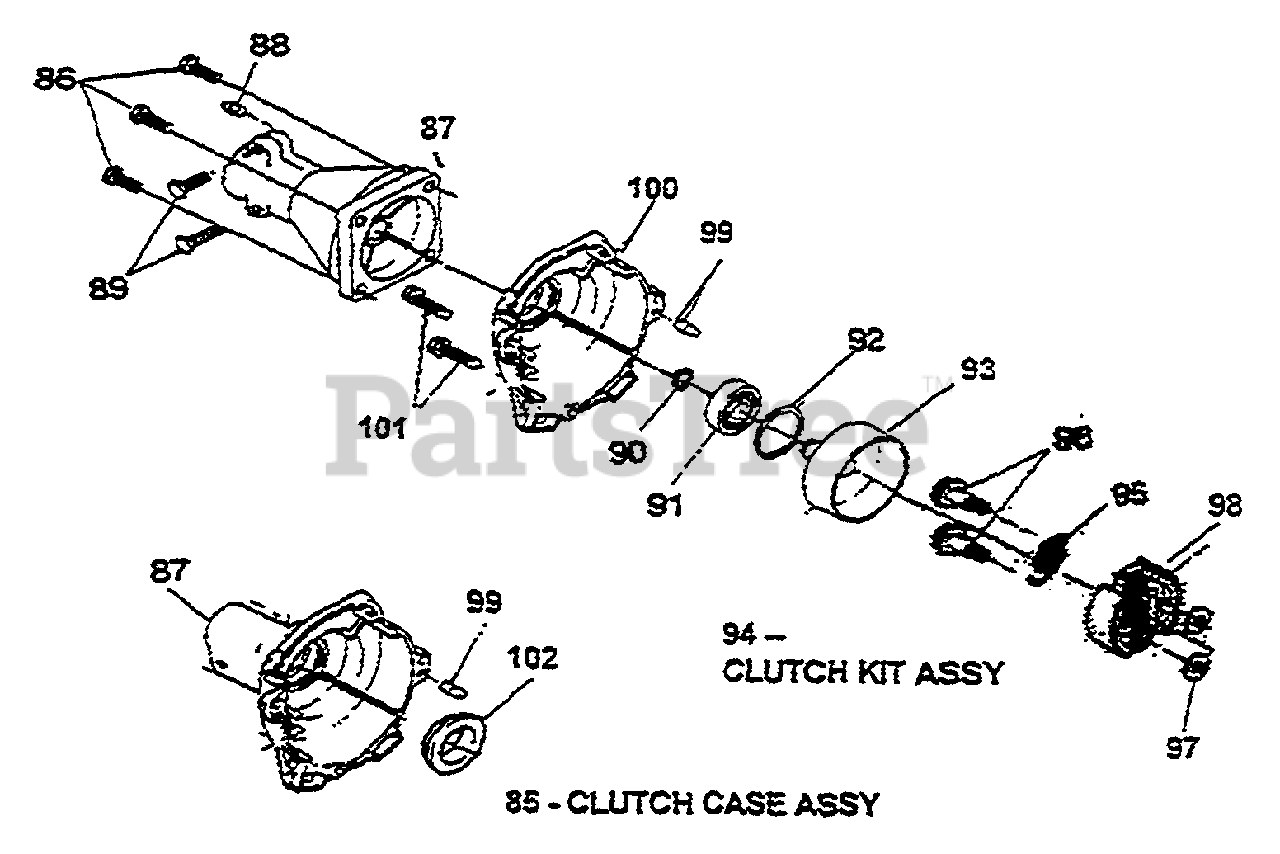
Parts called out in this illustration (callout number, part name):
85	CLUTCH CASE ASSY
86	BOLT & WASHER
87	CASE, CLUTCH
89	BOLT & WASHER
90	SNAP RING
91	BALL BEARING
92	SNAP RING
93	CLUTCH DRUM
94	CLUTCH SHOE ASSY
95	CLUTCH SPRING
98	CLUTCH SHOE
99	DOWEL PIN
100	CASE COVER
